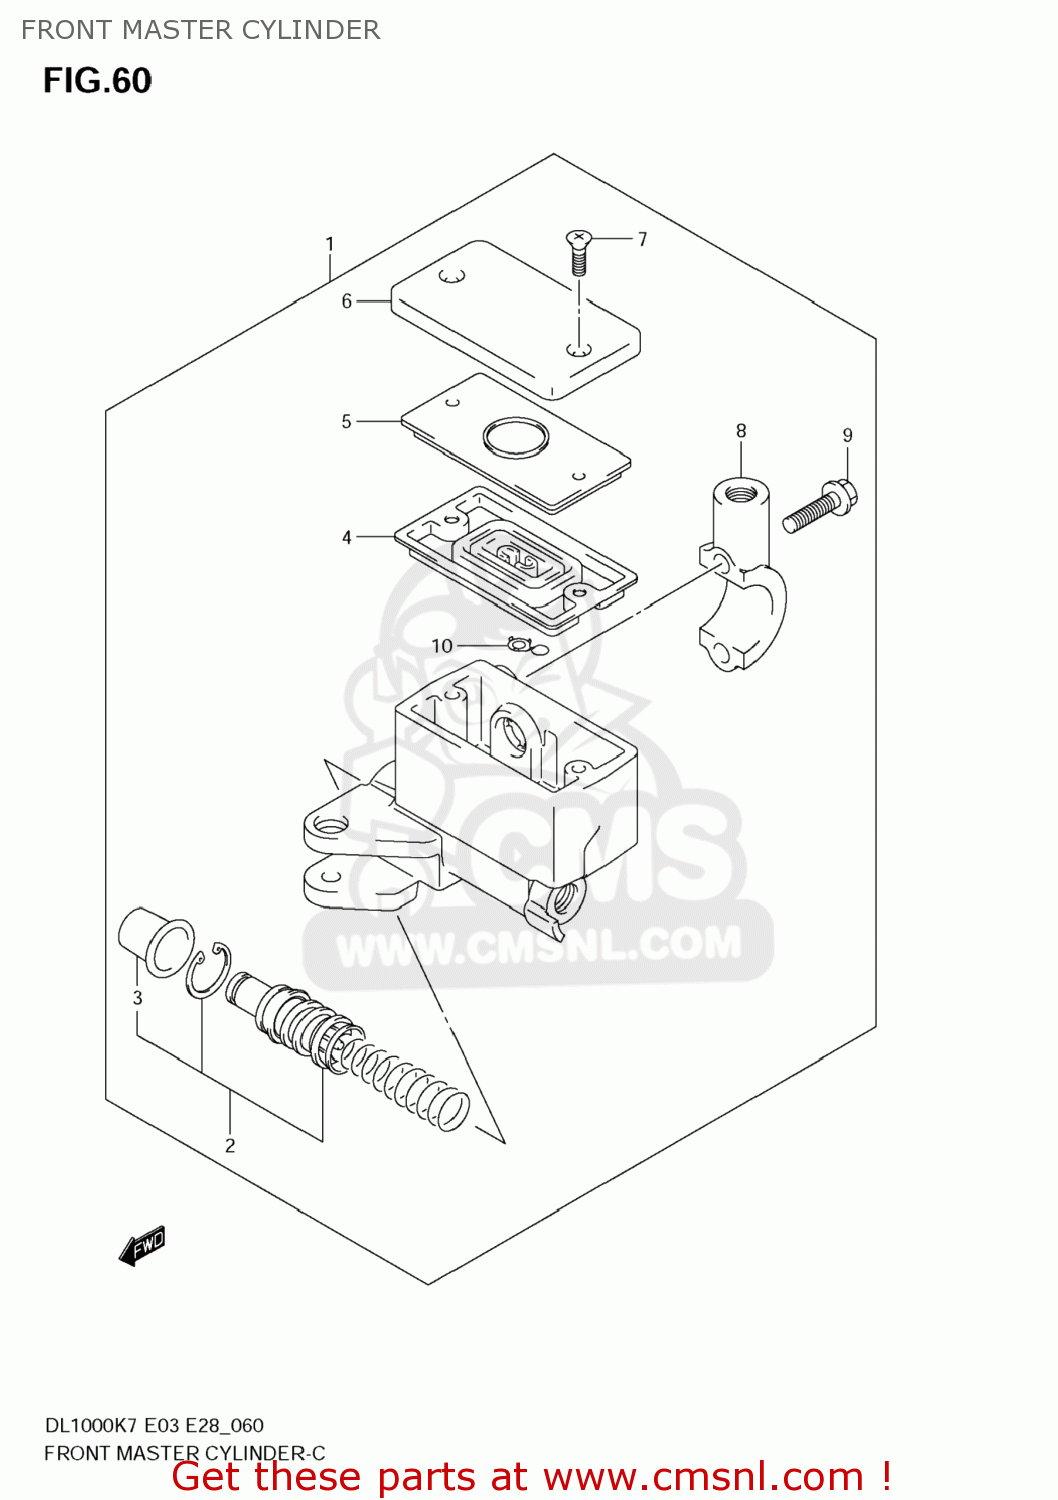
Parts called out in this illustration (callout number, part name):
1	CYLINDER ASSY,FR MASTER
2	PISTON & CUP SET
3	BOOT
4	5
5	PLATE,DIAPHRAGM
6	CAP
7	SCREW
8	HOLDER
9	BOLT(6X22)
10	PROTECTOR
